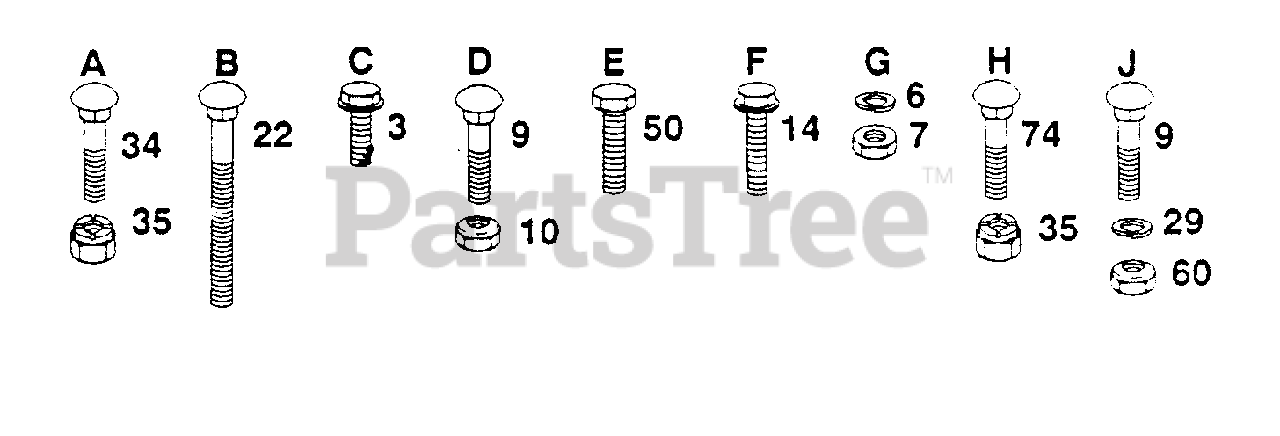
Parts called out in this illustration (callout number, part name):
3	Screw, Hex Washer Thr. Roll 5/16-18 x 1/2
6	Washer, Lock 5/16
7	Nut, Hex 5/16-18
9	Bolt, Carr. 5/16-18 x 3/4
10	Locknut 5/16-18
14	Screw, Hex Washer Thrd. Roll 3/8-16 x 3/4
22	Bolt, Carriage 5/16-18 x 2-3/4
29	Washer 11/32 x 3/4 x 16 Gauge
34	Bolt, Carriage 3/8-16 x 3/4
35	Nut, Crownlock 3/8-16
50	Bolt, Hex 3/8-16 x 1-3/8
60	Locknut 5/16-18
74	Bolt, Carriage 3/8-16 x 1
